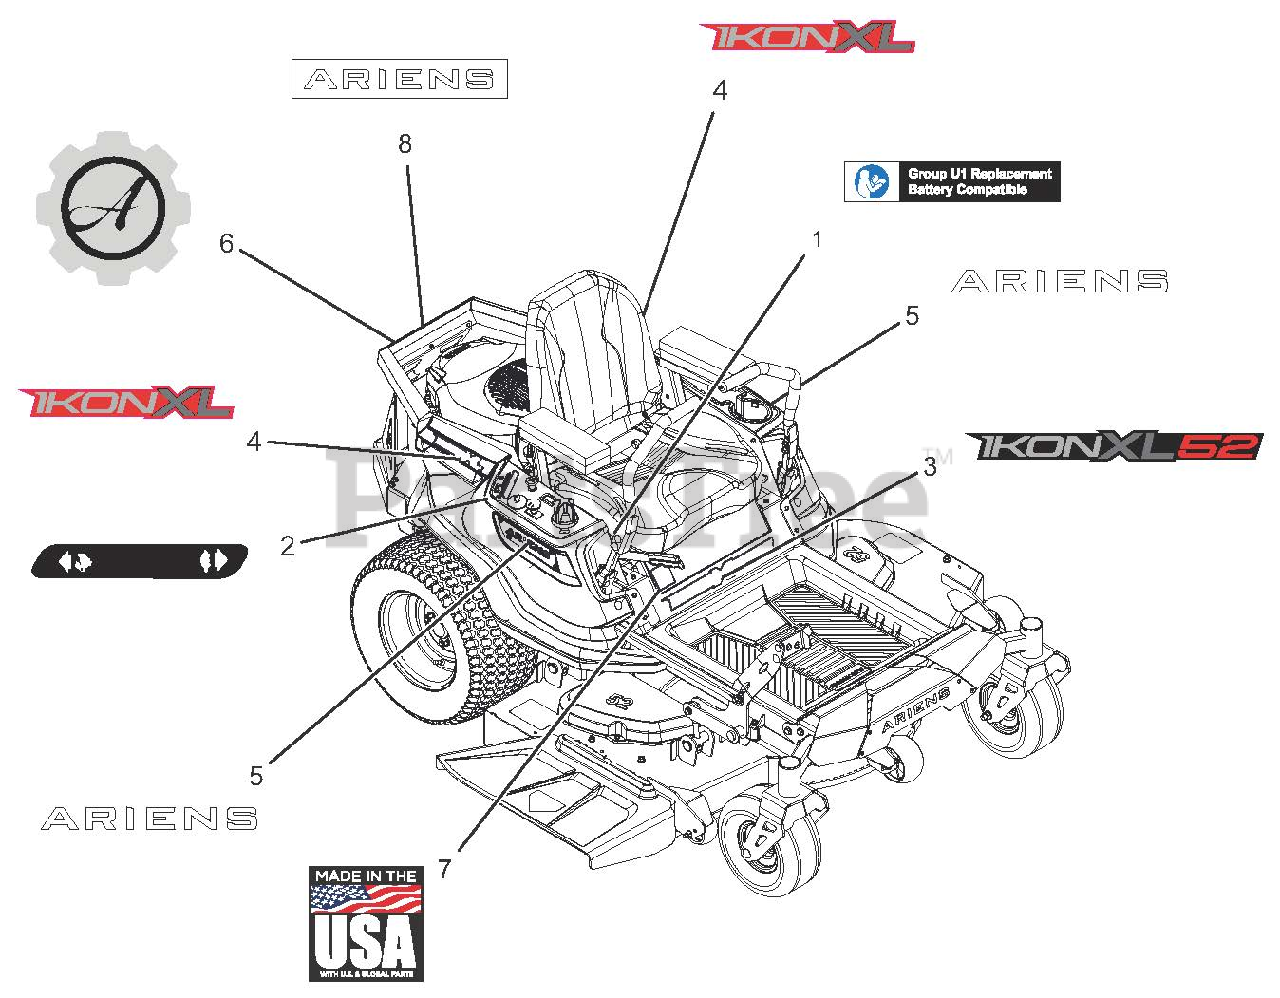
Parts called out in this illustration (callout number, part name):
1	DECAL, U1 BATTERY REPLACEMENT
2	DECAL, DASH DECAL
3	DECAL, IKON-XL 52"
4	DECAL, IKON-XL
5	DECAL, ARIENS (6.50")
6	DECAL, ARIENS-GEAR BADGE
7	DECAL, MADE IN USA
8	DECAL - ARIENS 9.625"
